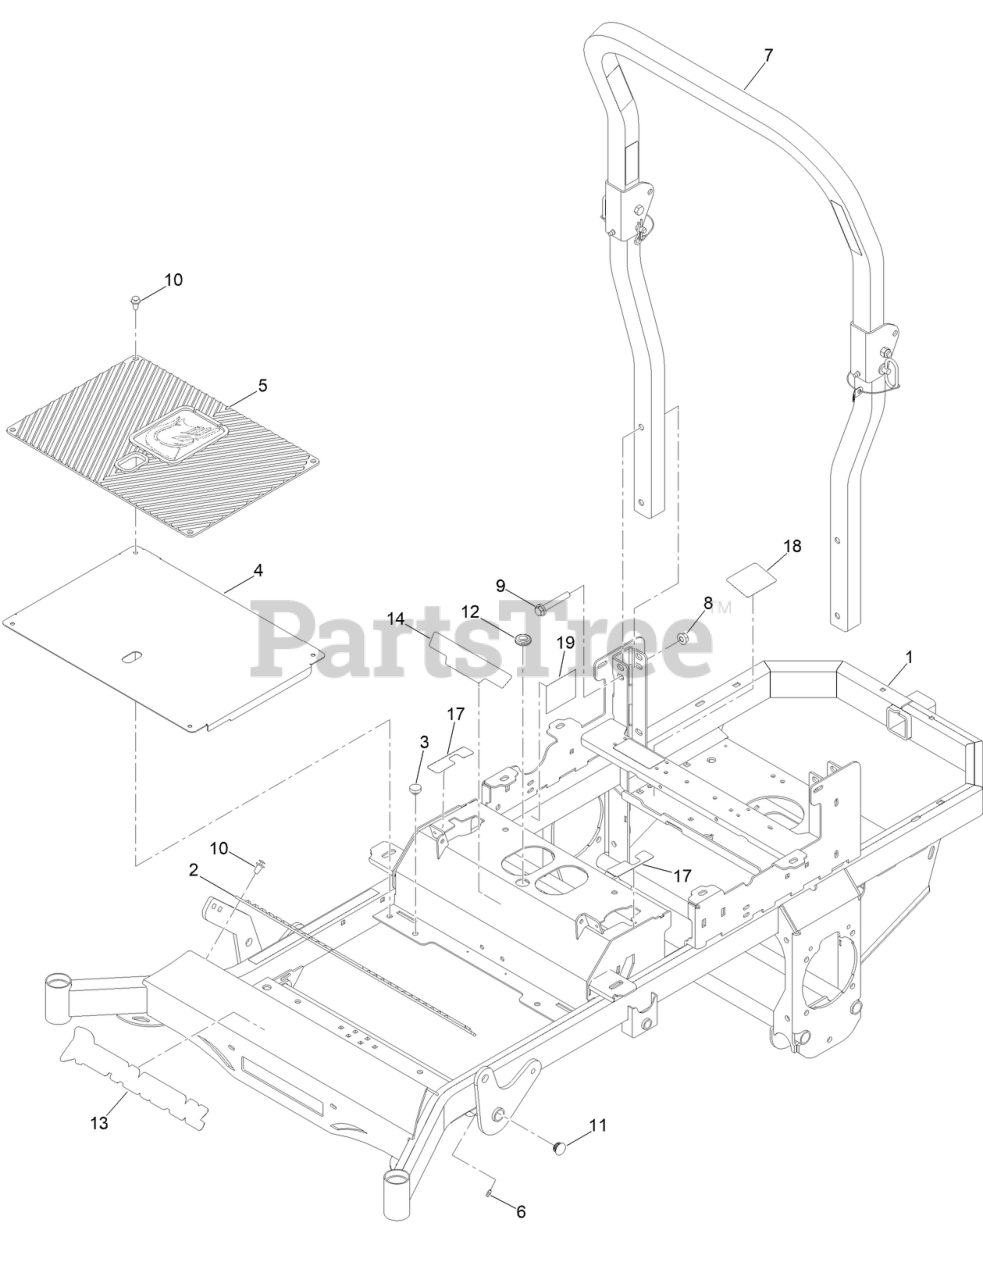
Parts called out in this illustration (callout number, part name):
1	ASM FRAME W/ DECALS
2	MWR RUBBER FOOT REST MAT
3	PUSH-IN RUBBER BUMPER MWR FLOOR
4	MWR FLOORBOARD PAINT
5	MWR LOGO FLOOR MAT
6	1/4 DRIVE TYPE STRAIGHT GREASE FITTNG ZC
7	MWR FOLD DOWN ROPS
8	1/2-13 HEX STOVER LOCKNUT GR C ZINC
10	8MM PUSH TYPE RETAINER NYLON BLACK
11	1-1/4 IN ROUND TUBE PLUG
12	GROMMET-RUBBER
13	DECAL-SPARTAN, FRONT
14	2022 RT-PRO W/GT TRAC DECAL
17	DECAL-MOTION CONTROL
18	DECAL-PUMP BELT ROUTING-TUFF TORQ
19	DECAL-E P A
